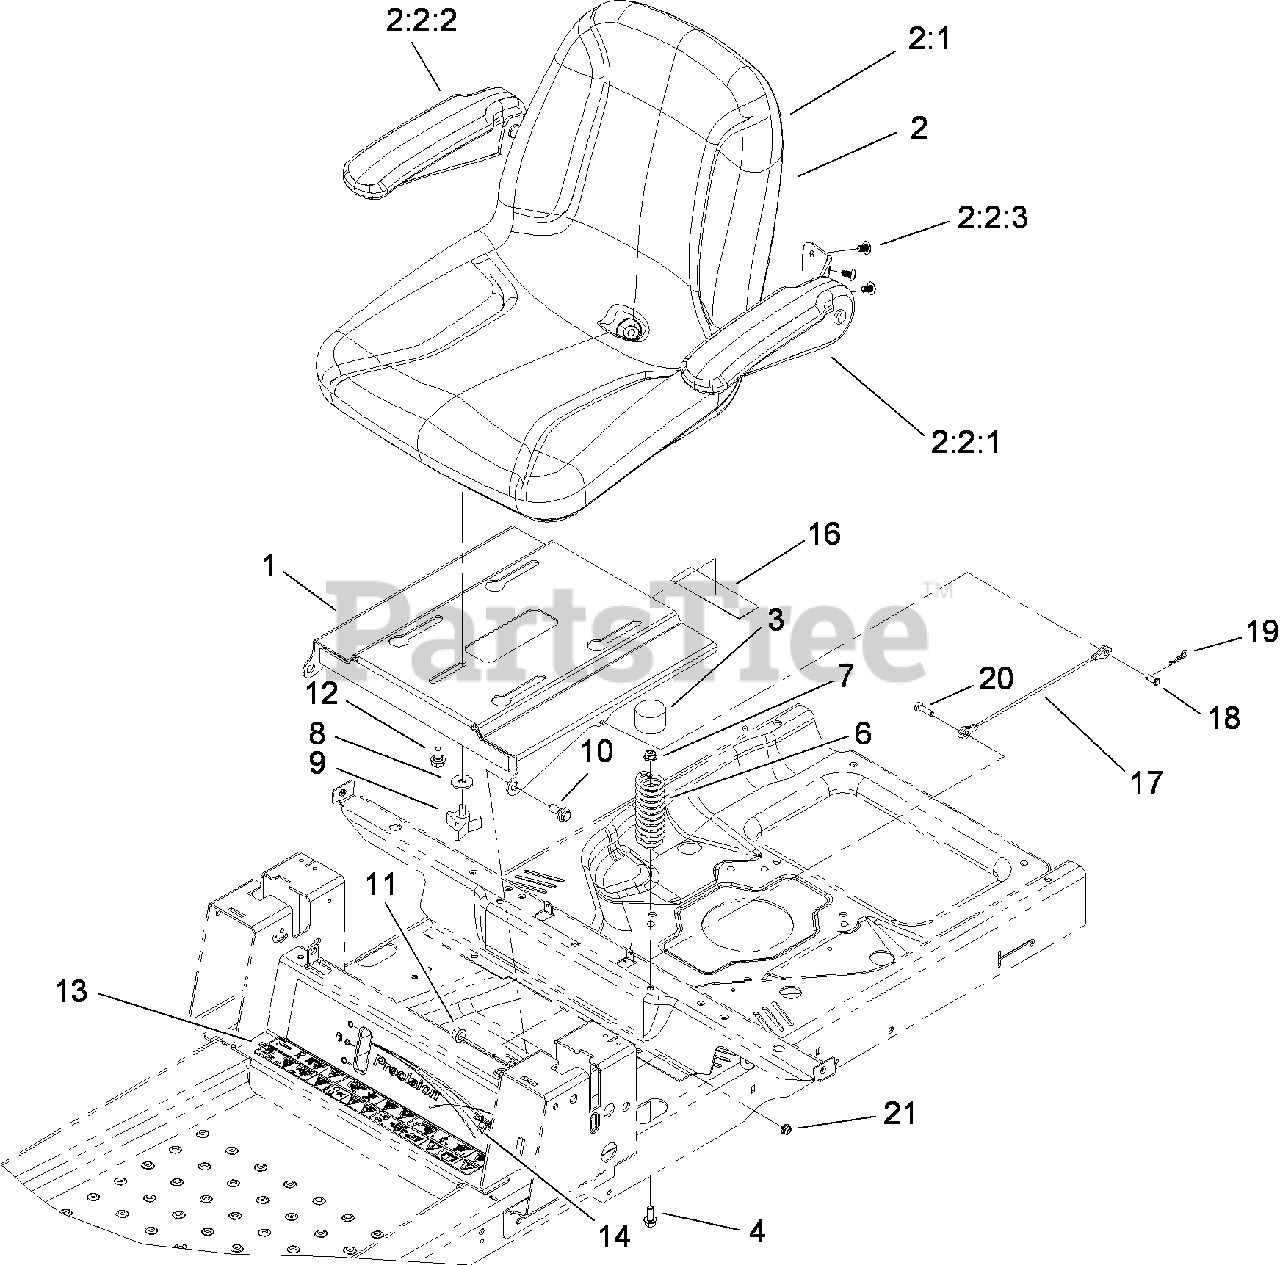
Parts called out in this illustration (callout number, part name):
2	18 INCH SEAT ASM (W/ARM RESTS)
2:1	SEAT-18 INCH
2:2:1	LH ARMREST KIT
2:2:2	RH ARMREST KIT
2:2:3	SCREW-HSBH
3	CAP-PROTECTOR
4	SCREW-HHF
6	SPRING-COMPRESSION
7	NUT-FLANGE, NI
8	WASHER-PIVOT
10	BOLT-SHOULDER
12	BOLT-SHOULDER
13	DECAL-DANGER
16	DECAL-SERVICE
17	CABLE-STOP, SEAT
18	PIN-CLEVIS
19	PIN-COTTER, HAIR
20	SCREW-HH
